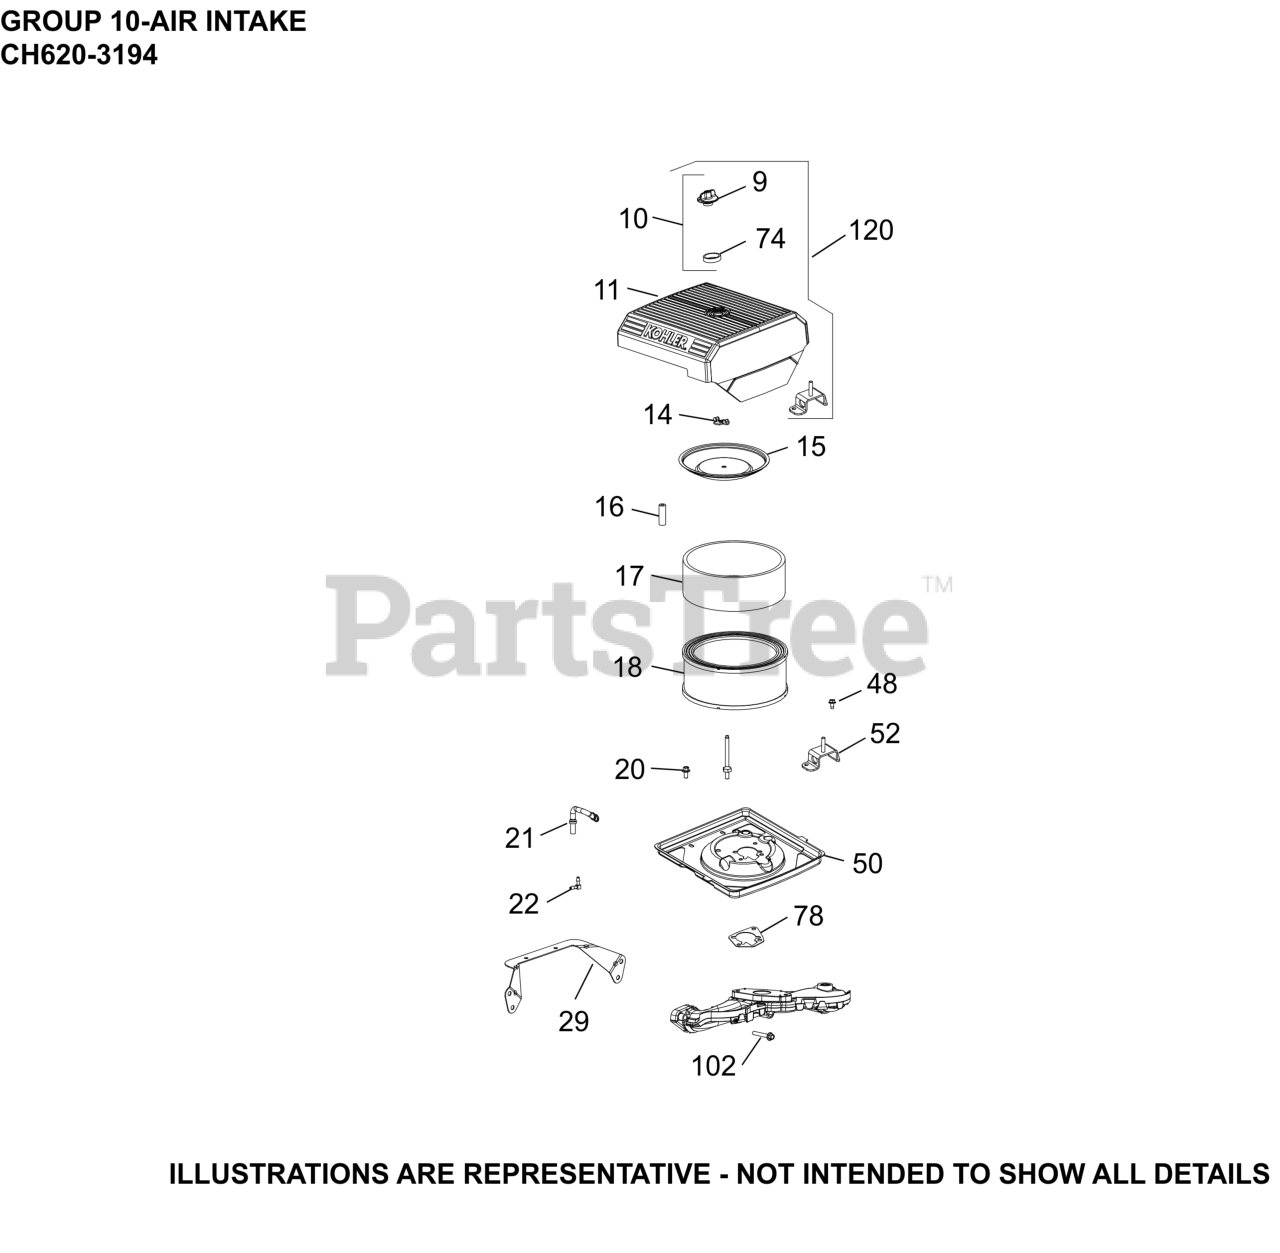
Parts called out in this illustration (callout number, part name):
9	KNOB, COVER
10	KIT, KNOB W/SEAL
11	COVER, AIR CLEANER
14	NUT, WING
15	COVER, INNER AIR CLEANER
16	SEAL BREATHER
17	PRE-CLEANER (HIGH)
18	AIR FILTER ELEMENT
20	SCREW, FLG THD FRM M6X1.0X16
21	HOSE, EVAP
22	CONNECTOR, EVAPORATIVE HOSE
29	AIR CLEANER BRACKET
48	SCREW, THREAD FORMING
50	KIT, AIR CLEANER BASE
52	BRACKET, AIR CLEANER
78	GASKET, AIR CLEANER BASE
102	SCREW, FLG M6X1.0X40
120	KIT, AIR CLEANER COVER
